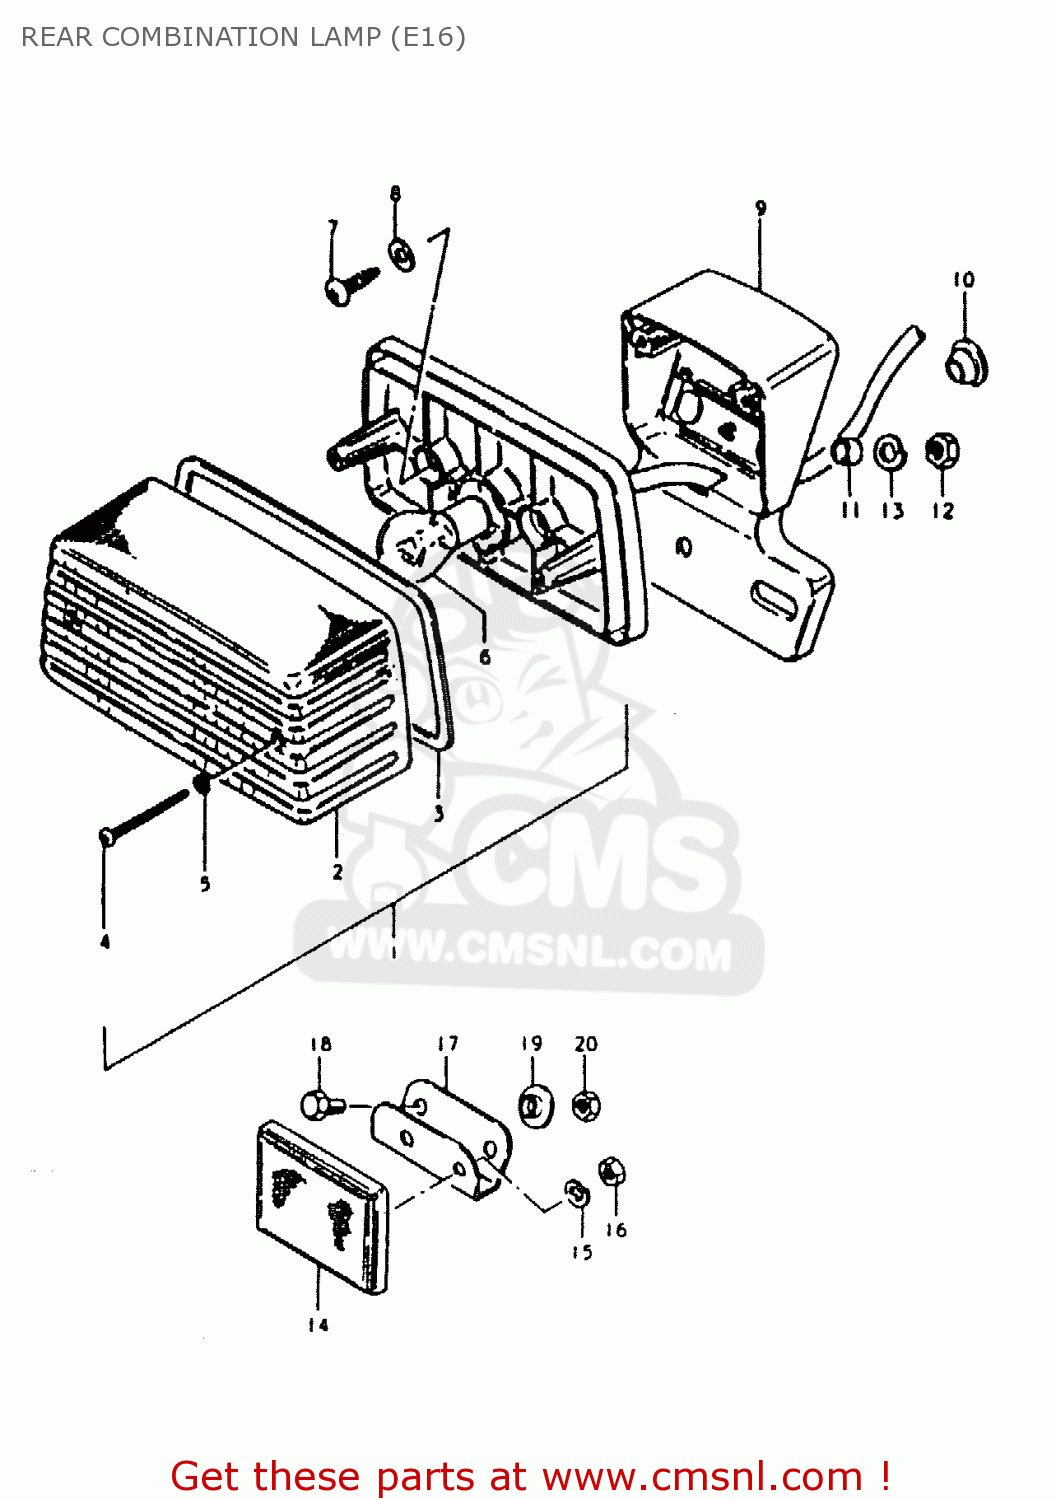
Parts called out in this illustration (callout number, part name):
1	LAMP UNIT, TAIL
2	LENS
3	GASKET (NAS)
4	SCREW
5	GASKET (NAS)
6	BULB (6V,21/5W)
7	SCREW
8	WASHER
9	BRACKET ASSY
10	GROMMET
11	SPACER(6.1X9X7.5)
12	NUT
13	LOCK WASHER
14	REFLEX REFLECTOR,RR
15	LOCK WASHER
16	NUT
17	BRACKET
18	BOLT
19	SPACER
20	NUT
